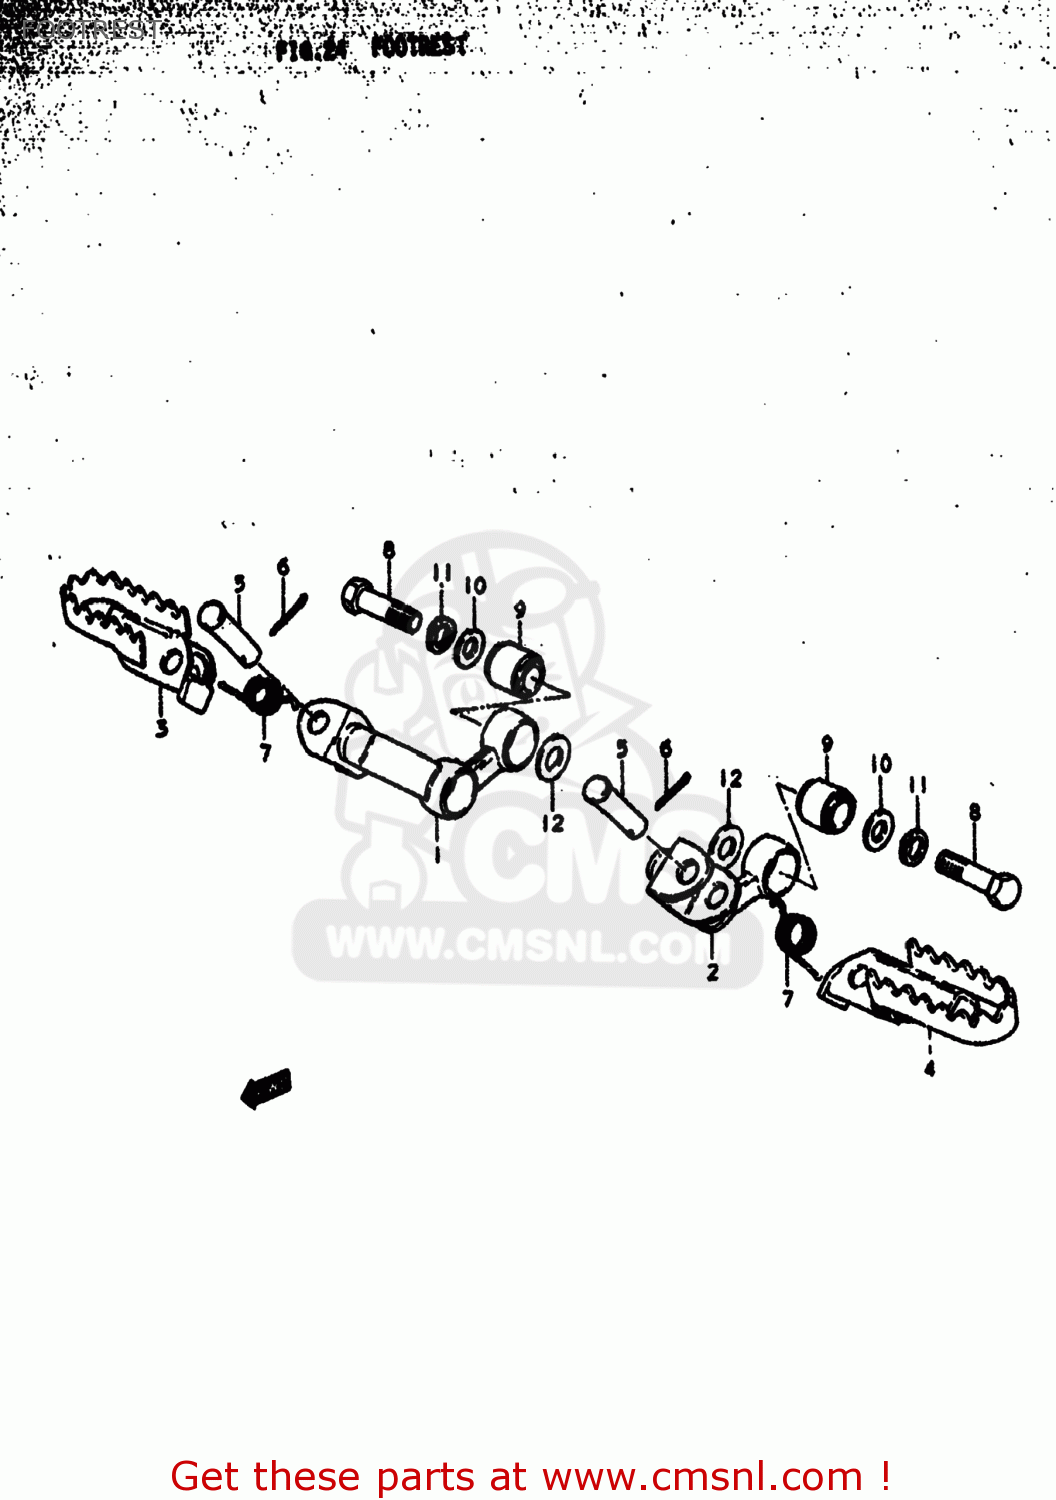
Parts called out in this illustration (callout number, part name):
1	BAR,FRONT FOOTREST
2	BRACKET COMP,FRONT FOOTREST
3	FOOTREST,FR,R
4	FOOTREST,FR,L
5	PIN
6	PIN 20X20
7	SPRING
8	BOLT
9	BUSH
10	WASHER
11	LOCK WASHER
12	WASHER (10.1X21X2.3)
